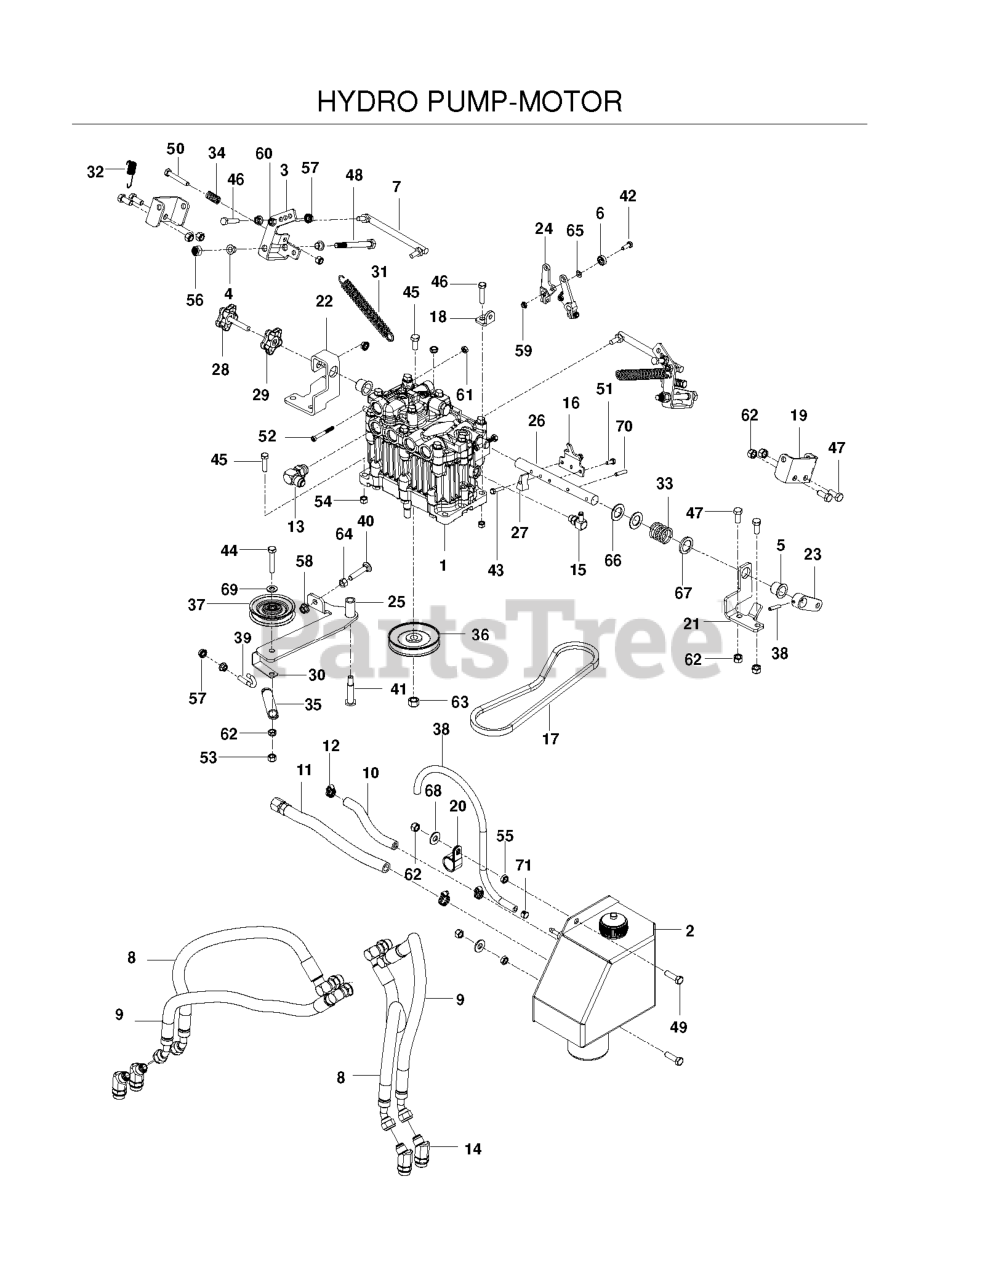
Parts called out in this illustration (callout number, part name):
1	PUMP, DUP10E
3	BELLCRANK LH PAINTED
4	BEARING - FLANGE 10MM
5	BEARING - FLANGE, 20MM
6	BEARING - FOLLOWER
7	LINK - CONTROL, RH WB
10	HOSE - RETURN
11	HOSE - SUCTION
12	HOSE CLAMP T-1865
13	ELBOW, 90 DEGREE
14	45 DEG STRAIGHT THD ELBOW 8-10
15	FITTING, 90 DEG 9/16-18 X 3/8
16	PLATE - STOP, BLK
17	V-BELT PUMP DRIVE
18	BRACKET, SPRING, BLK
19	BRACKET - U
21	SUPT - CAM LH
22	SUPT - CAM, RH PAINTED
23	ARM - SPEED CONTROL
24	ARM - HYDRO
26	SHAFT - CAM
27	CAM - TRACKING
28	KNOB, ADJUSTING
30	KEEPER, BLK
31	SPRING-TRANS
32	SPRING, EXTENSION
33	SPRING - COMPRESSION
35	SPRING AXLE AERATOR
36	PULLEY, PUMP
40	RHSNB 3/8C X 2
41	BOLT, SHOULDER
42	HCS 1/4C X 3/4 HCS
43	BOLT - M6-1.0 X 30MM GR 8
44	HCS 3/8C X 2
45	HCS 5/16C X 1 1/4
46	CAPSCREW 5/16 X 1/1/2 HEX HEAD
47	HCS 3/8-16 X 7/8 GR 5 ZD
48	HCS M10-1.58 X 100MM GR8.8 ZD
49	HCS 3/8C X 1 1/4 GR5
50	HCS 5/16-18X2
51	HCS M6-1.0 X 16MM GR 8.8 ZN
52	SCR, #10-24X2 SOCKET HEAD CAP
53	NUT HEX 3/8-16 NYLON, THIN
54	NUT 5/16 NYLOC
55	NUT 3/8-16
56	NUT, M10-1.5 NYLON RING ZD
57	NUT 5/16C WHIZ
58	NUT 3/8C WHIZ
59	JAM NUT 1/4C (2 2 PW01)
60	NUT M8-1.25 TOP NYL GR10 ZD
61	NUT 10-24 NYLOC
62	NUT 3/8-16 NYLOC
63	NUT M10-1.5 L/H HEX
64	NUT 3/8-16 HEX JAM
66	WASHER - 20MM
67	WASHER, FIBER
68	WASHER 3/8 FLAT
69	WASHER 3/8 SAE FLAT
70	ROLL PIN - 6 MM X 30 MM
71	HOSE CLAMP
